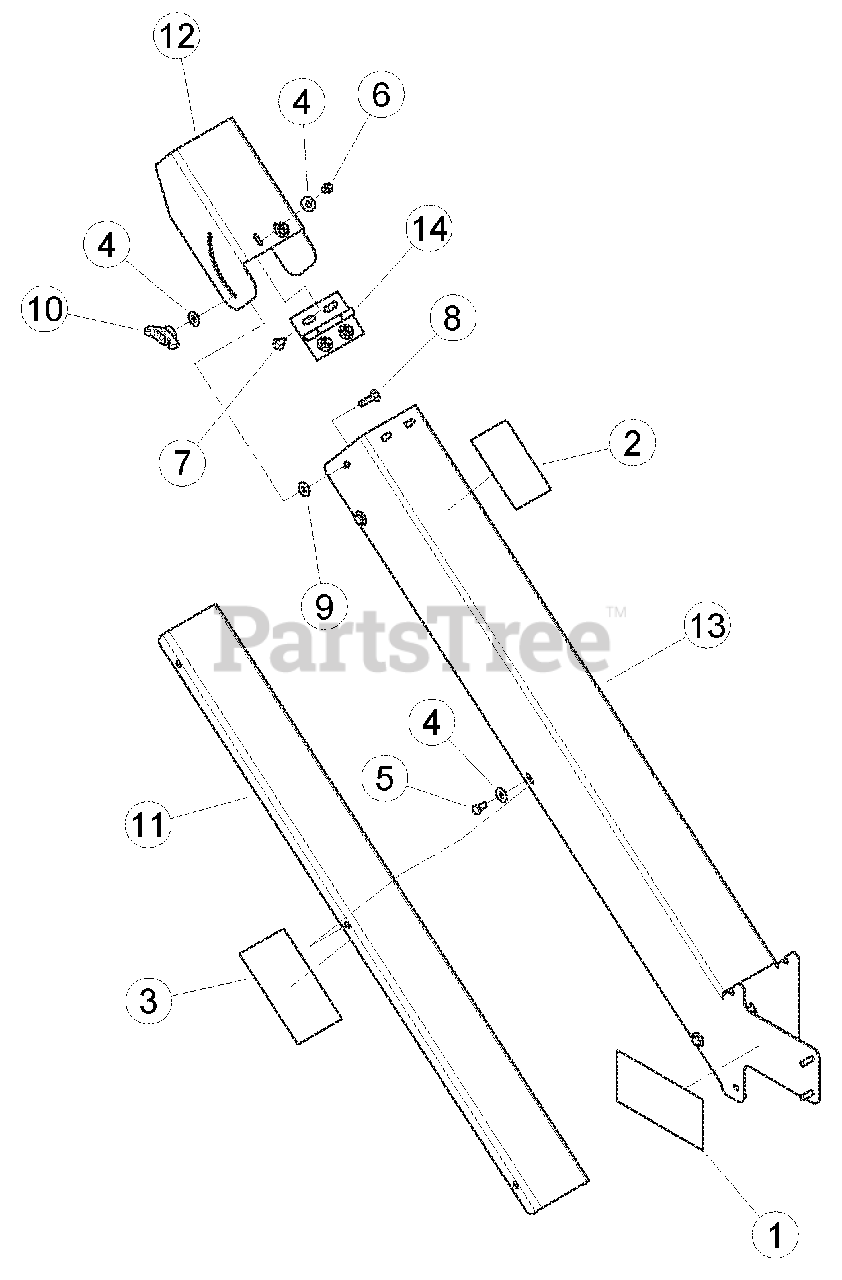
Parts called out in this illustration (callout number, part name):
1	DECAL, KNIFE ACCESS ISO
2	DECAL, DISCHARGE ISO
3	DECAL, BLADE DANGER ISO
4	WASHER, 5/16 FLAT ZP
5	BOLT, 5/16 X 5/8 HEX HD GR5 ZP
6	NUT, 5/16 NE NYLOCK ZP
7	BOLT, 5/16 X 3/4 CRG GR5 NC ZP
8	BOLT, 5/16 X 1-1/4 CRG GR5 ZP
9	WASHER, 5/16"ID 7/8"OD NYLON FLAT
10	KNOB, 5/16-18 UNC TEE W/LOCKING INSERT
11	WELDMENT, TOP DISCHARGE CHUTE
12	CAP, DISCHARGE
13	WELDMENT, CHIPPER DISCHARGE
14	HINGE, DISCHARGE CAP
